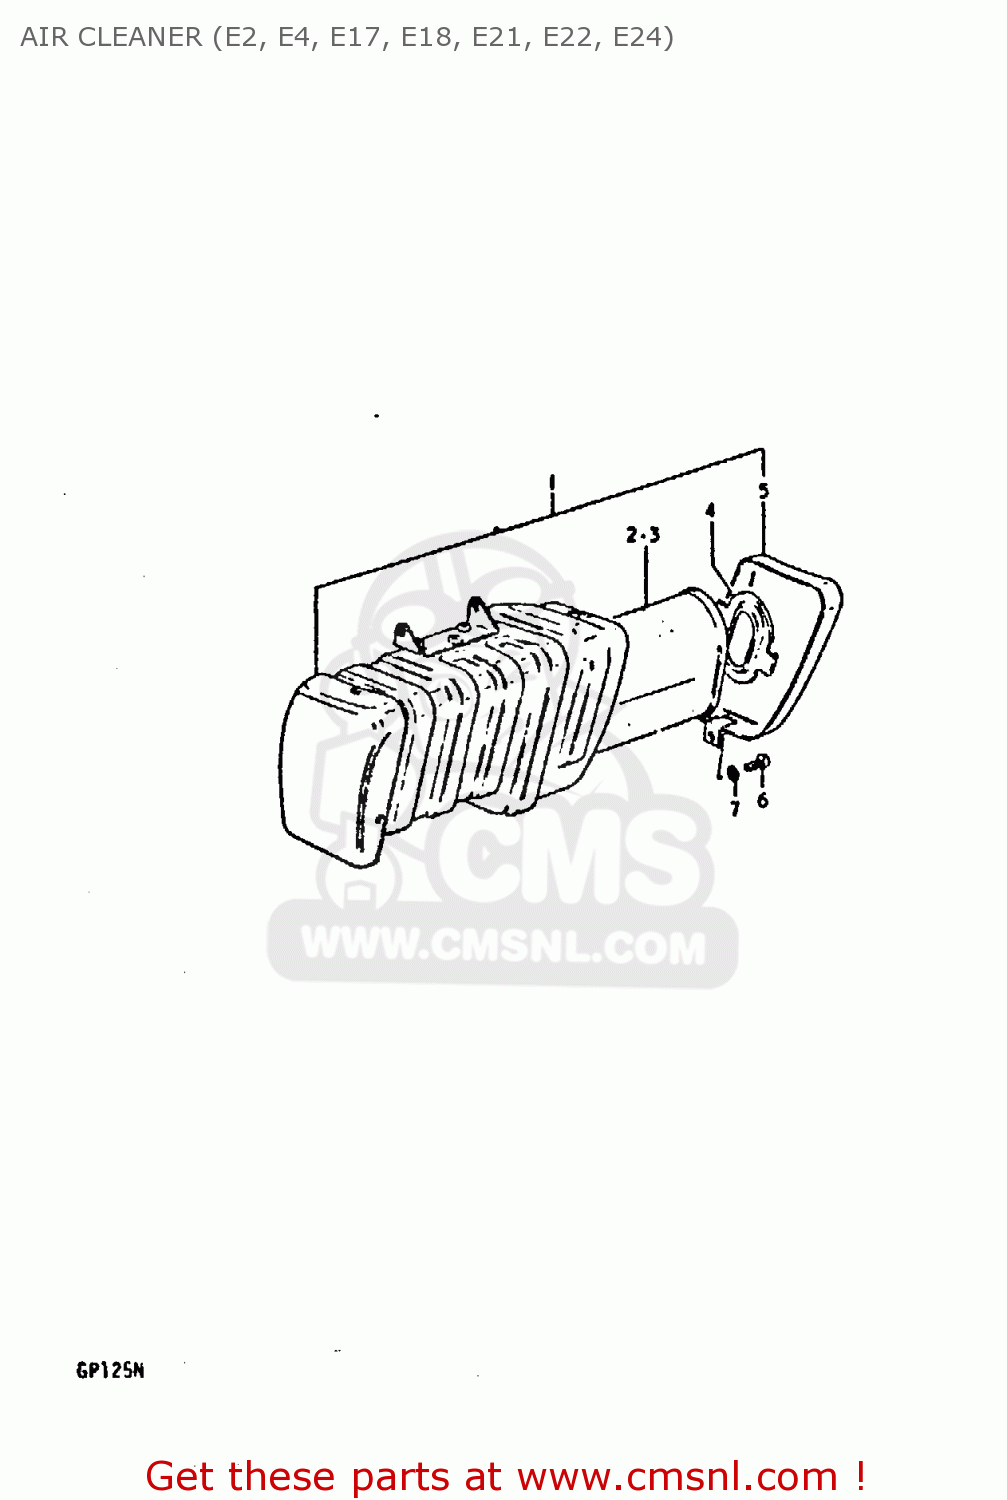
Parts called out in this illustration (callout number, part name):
1	CLEANER ASSY, AIR
2	FILTER ASSY,AIR CLEANER
3	FILTER
4	HOLDER
5	COVER
6	SCREW
7	LOCK WASHER
